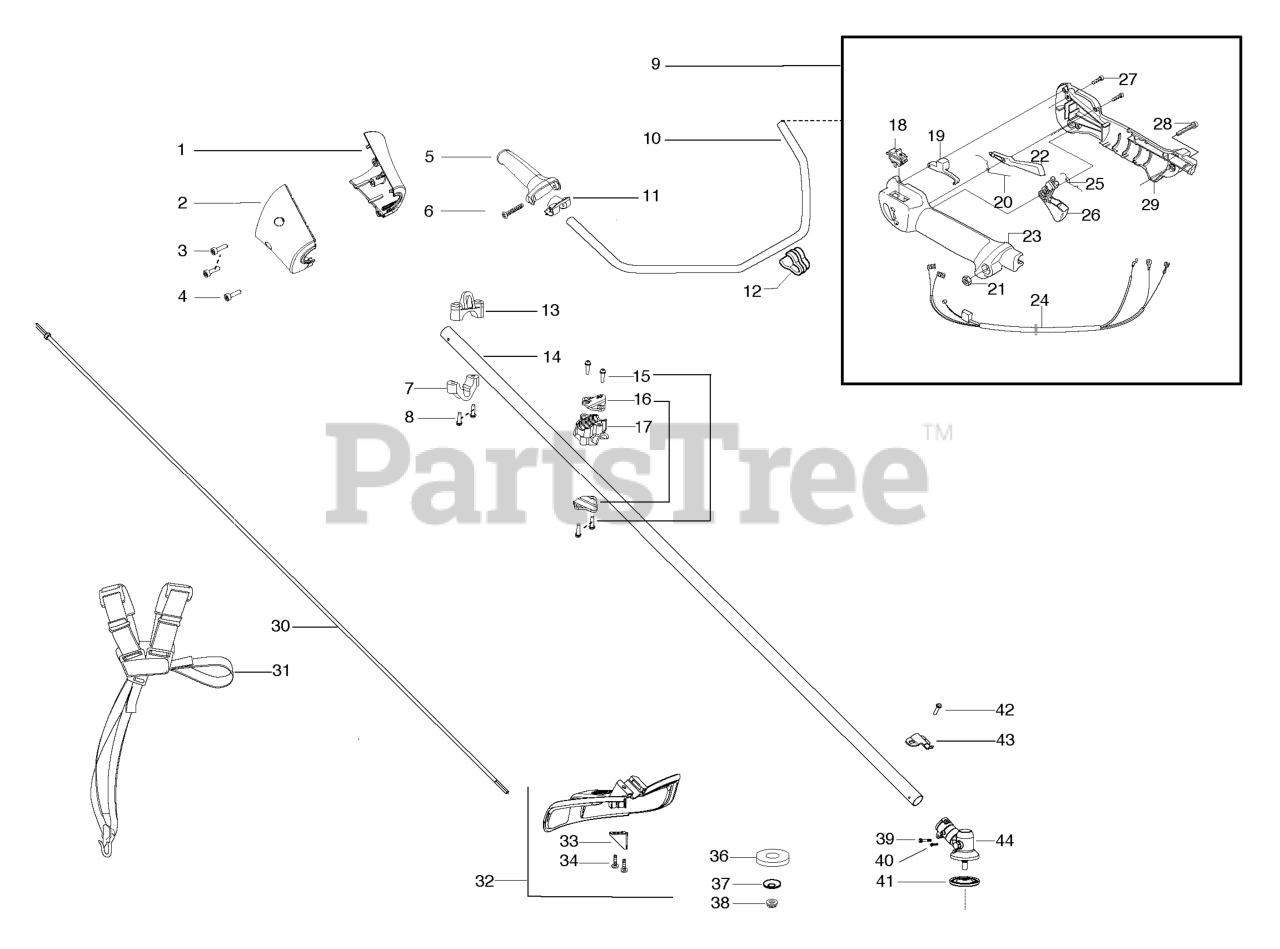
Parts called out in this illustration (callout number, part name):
1	NOSE CONE BH LEFT
2	NOSE CONE BH RIGHT
4	SCREW M4 X 1.75 PT 16MM
7	CLAMP HARNESS LOWER
9	ASSY THROTTLE HOUSING
13	CLAMP HARNESS UPPER
14	KIT D'SHAFT
16	CLAMP BRACKET
18	KIT SWITCH
19	LOCKOUT STARTER THROTTLE
22	THROTTLE LOCK
24	THROTTLE CABLE
26	THROTTLE TRIGGER
28	SCREW
30	FLEXSHAFT 57"
31	HARNESS DUO
32	KIT COBI SHIELD
33	Limiter - Line
36	SUPPORTING CUP
37	SUPPORT FLANGE
38	GEARHEAD NUT - BRUSHCUTTER
39	SCREW - CARB. ADAPTOR
41	DRIVE DISC
42	SCREW 1/4-20 X 7/8 (TAP
43	BRACKET SHIELD STRAIGHT SHAFT
44	ASSY GEARBOX
